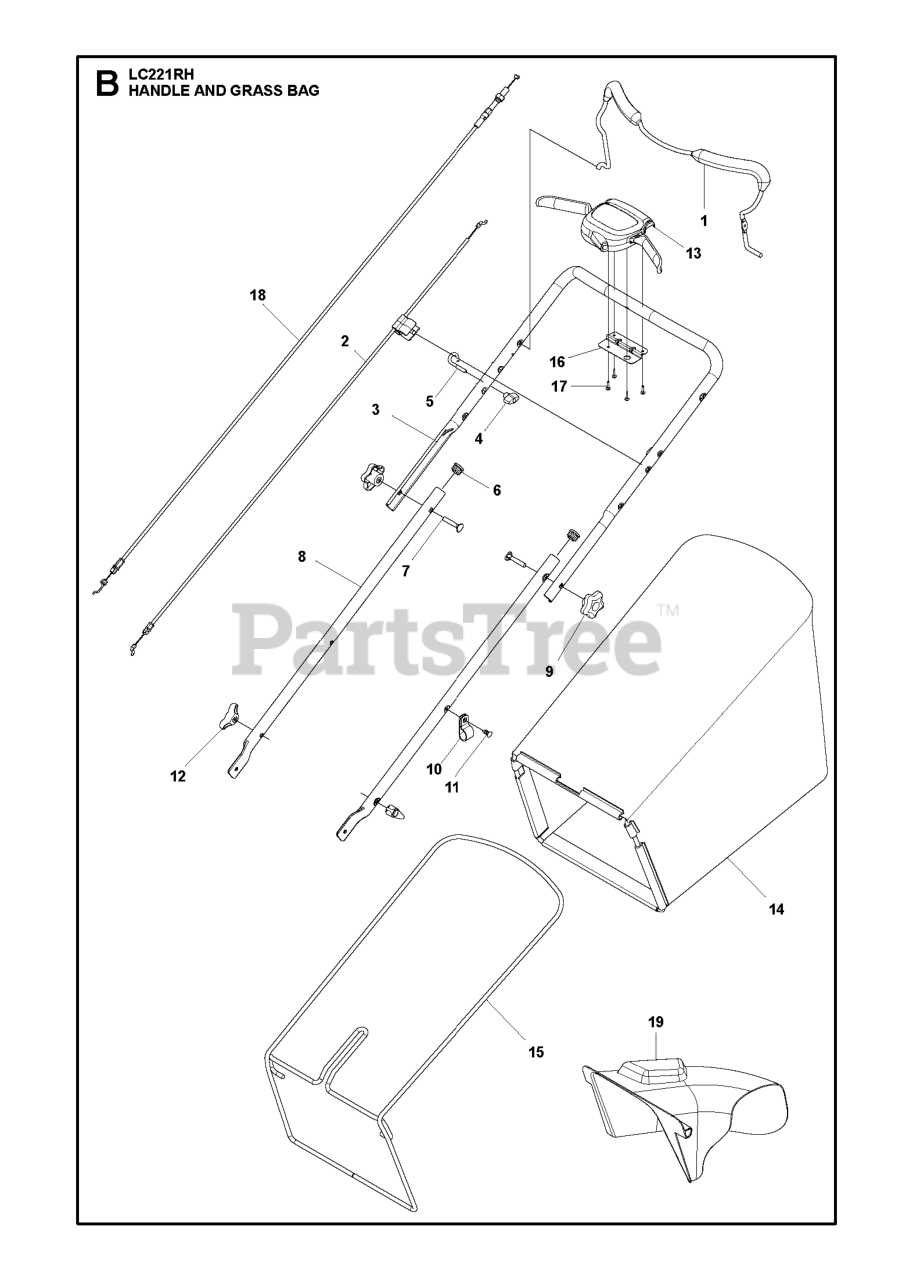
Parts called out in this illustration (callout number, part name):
1	BAIL.OM.ERGO.BENT.MZR.ORAN.668
2	CABLE.MZR.50.SNAP-IN
3	HANDLE.UPPER.3.POS.BS.AW2.GREY
4	T-KNOB.NEW ROPE GUIDE
5	GUIDE.ROPE.BLK.ZINC.CHROM
6	PLUG.PLASTIC.7/8".14-20.GAUGE
7	BOLT.CONCAVE.HEAD.RETAINING
8	HANDLE.LOW.2PC.2POS.21EFF.498
9	KNOB.HANDLE.PLASTIC.STAR.BLACK
10	CLIP.CABLE.BLK
11	FASTENER.PUSH.O.250X0.783
12	KNOB, DEFLECTOR
14	GBAG.C361029ER.HUSQ.GRY.21EFF
15	FRAME.GBAG.AWD.21.BLACK
16	BRACKET DUAL TRIGGER CONTROL
17	SCREW, PHILLIPS HEAD 10 X 5/8
18	CABLE.DRIVE.21EFF.BS.RWD
19	CHUTE.DISCHARGE.21EFF.HW
